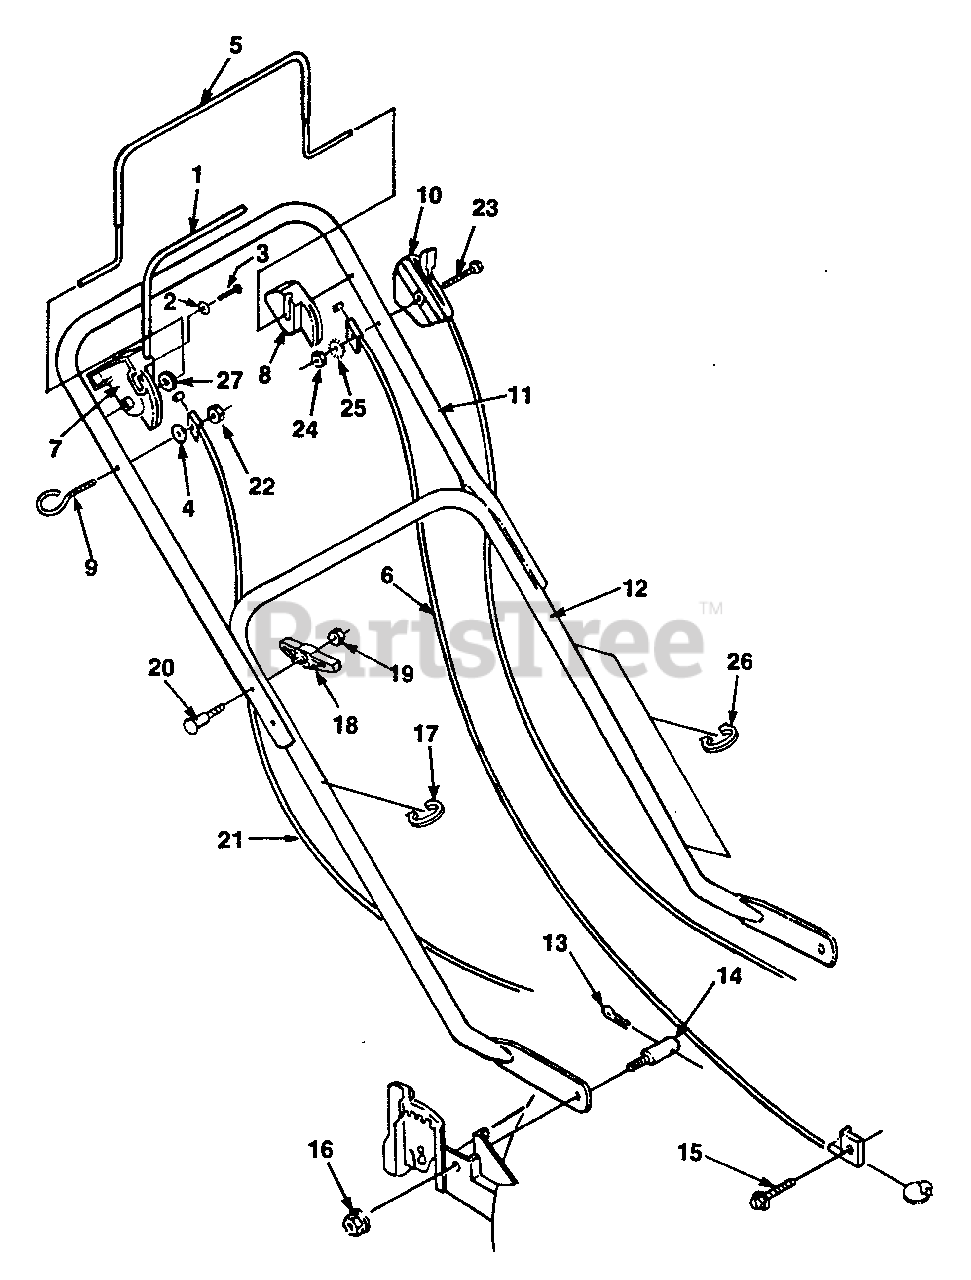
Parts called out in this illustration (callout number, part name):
1	TRACTION LEVER
2	WASHER - 1/4"
3	SCREW - 10-16 X 1/2"
4	WASHER - WAVE
5	BAIL - BRAKE CONTROL
6	CONTROL, MANUAL START
7	ACTUATOR - RIGHT
8	ACTUATOR - LEFT
9	EYEBOLT - (1/4-20 x 1 3/4")
10	CONTROL, THROTTLE
11	HANDLE - UPPER
12	HANDLE - LOWER
13	PIN, SPLIT
14	STUD
15	SCREW - 10-24 X 1/2"
16	NUT - 5/16-18 -- FLANGE
17	CLAMP - SINGLE
18	KNOB - Handle
19	NUT - 5/16-18
20	BOLT
21	CABLE - TRACTION CONTROL
22	LOCKNUT - 1/4-20
23	BOLT
24	NUT - 1/4-20
25	LOCKWASHER - 1/4" -- EXTERNAL
26	CLAMP - DOUBLE
27	WASHER - 5/16"
